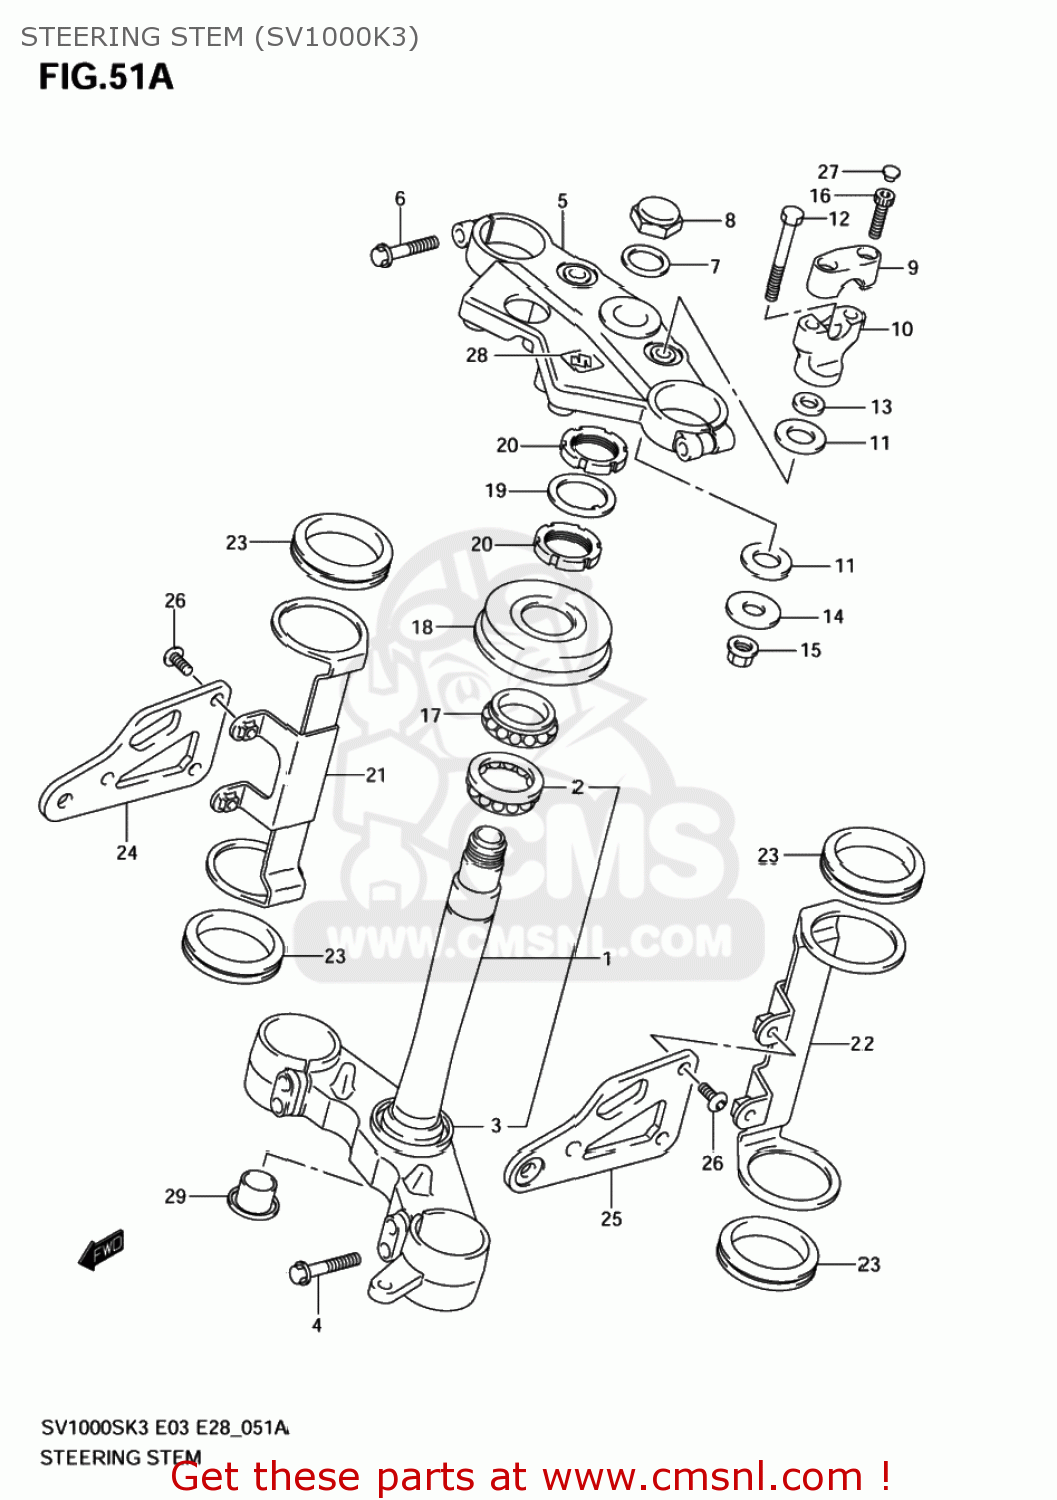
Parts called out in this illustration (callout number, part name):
1	STEM,STEERING
2	BEARING(30X55X17)
3	SEAL,STEERING LWR
4	BOLT
5	HEAD,STEERING STEM
6	BOLT
7	WASHER,STEM HEAD(24.5X34X1.6)
8	NUT
9	HOLDER,HANDLE
10	HOLDER,HANDLE LWR
11	RUBBER,HANDLE HOLDER
12	BOLT
13	WASHER
14	WASHER
15	NUT
16	BOLT,HOLDER UPR(07130-08307)
17	BEARING(30X55X17)
18	SEAL,STEERING UPR DUST
19	WASHER,STEERING STEM
20	NUT,STEERING STEM
21	BRACKET,HEADLAMP HOUSING
22	BRACKET,HEADLAMP HOUSING,L
23	DAMPER,HEADLAMP HSG BRACKET
24	STAY,HEADLAMP HOUSING,R
25	STAY,HEADLAMP HOUSING,L
26	SCREW(6X16)
27	CAP(OD:11)
28	EMBLEM,S
29	CAP
